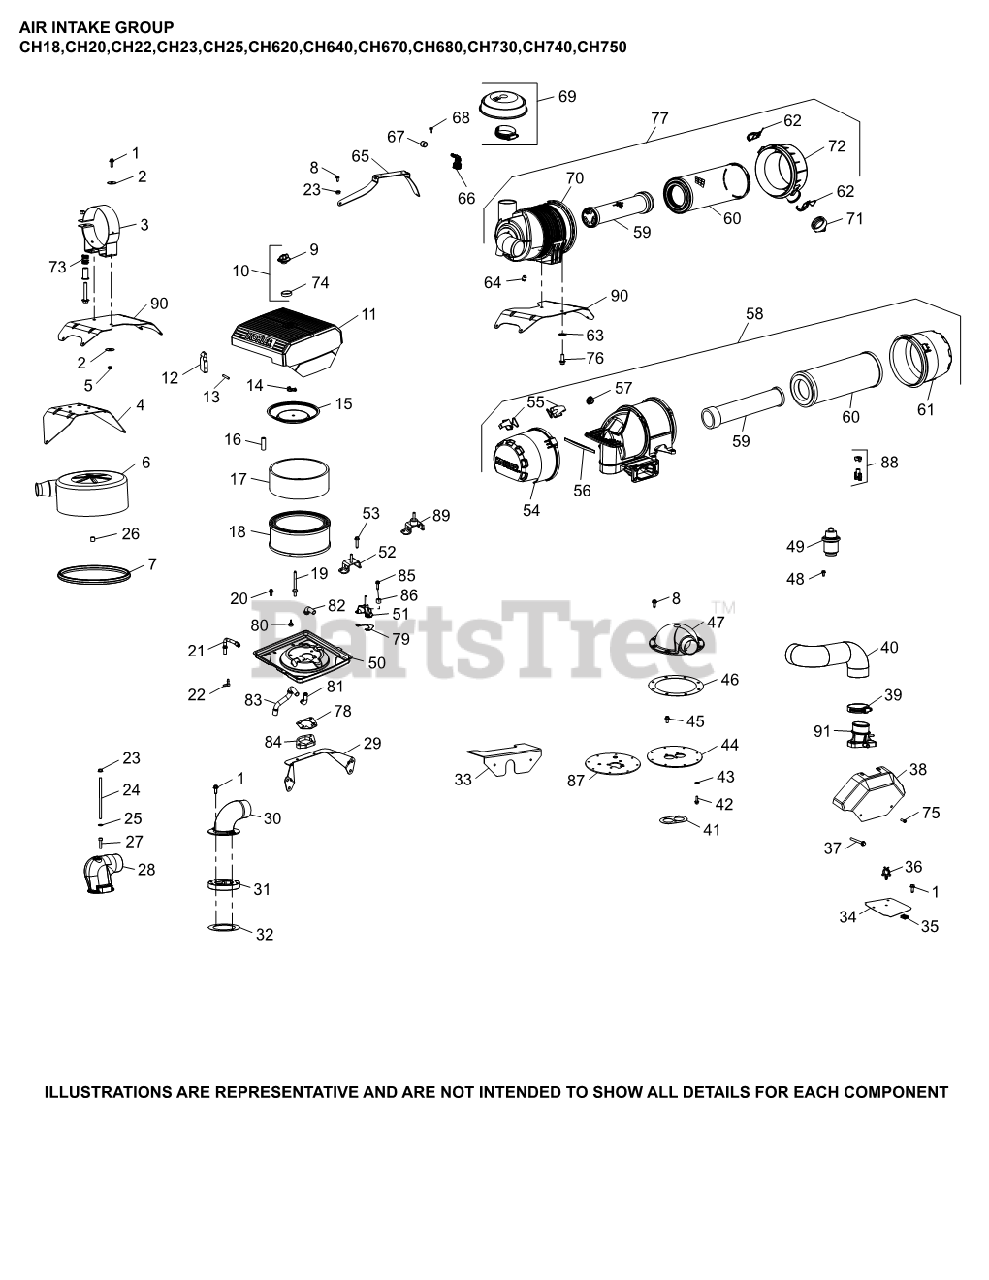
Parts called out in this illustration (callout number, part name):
6	COVER, AIR CLEANER
14	NUT, WING
15	COVER, INNER AIR CLEANER
16	SEAL, BREATHER
17	ELEMENT, PRECLEANER (LOW)
18	ELEMENT, AIR CLEANER - Also available Retail Packaged 47 883 03-S1 Air Filter Kit
20	SCREW, FLG THD FRM M6X1.0X16
21	HOSE, EVAP
22	CONNECTOR, EVAPORATIVE HOSE
50	KIT, AIR CLEANER BASE
52	BRACKET, AIR CLEANER
78	GASKET, AIR CLEANER BASE
